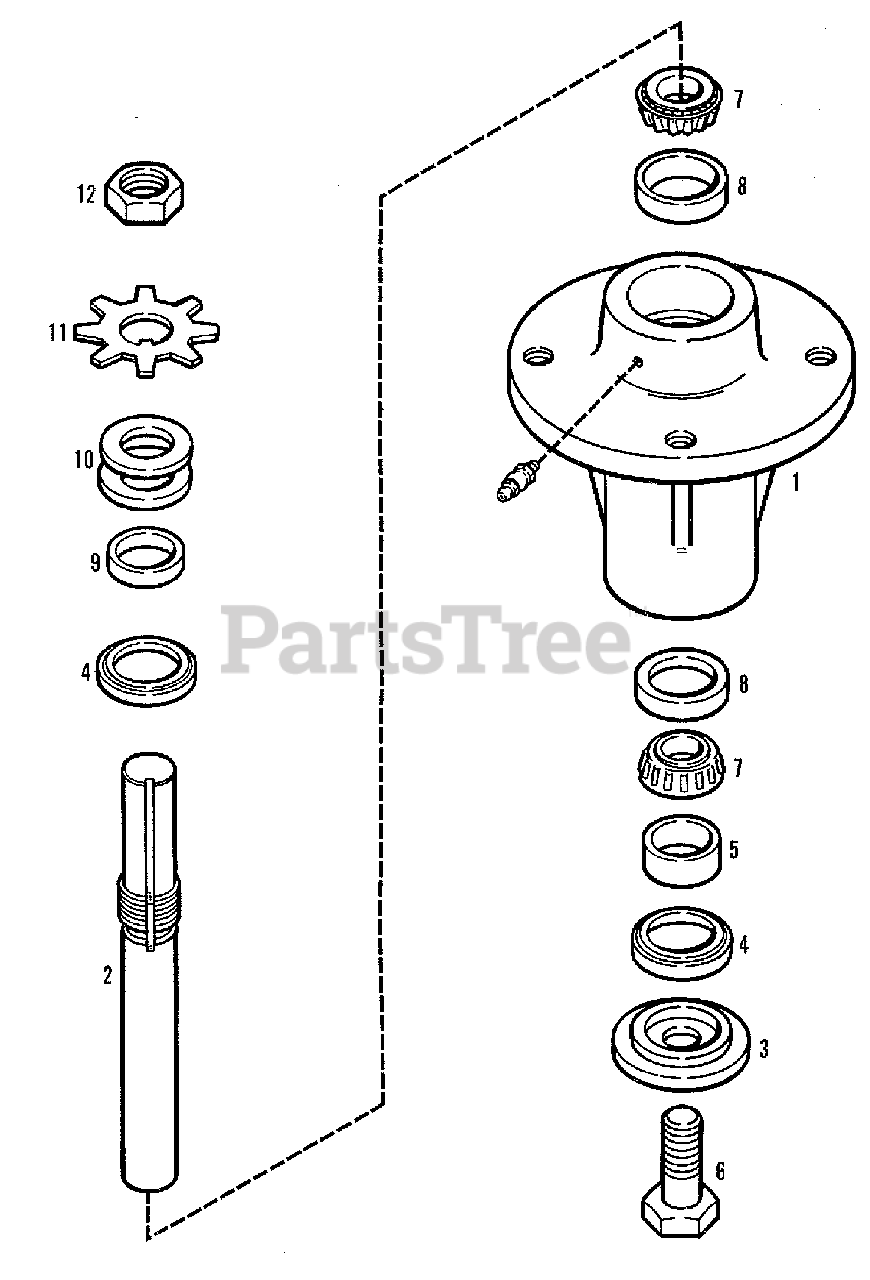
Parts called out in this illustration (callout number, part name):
1	HOUSING, Spindle
1	FITTING, Lube, 1/4-28 Straight
2	SHAFT, Spindle
3	WASHER, Shoulder
5	SPACER, Bottom
6	CAPSCREW, L.H. Thread, 5/8NC x 1-1/2
7	CONE, Bearing
8	CUP, Bearing
9	SPACER, Top
10	BUSHING, Machinery, 1" x 10 Ga.
11	WASHER, Star
